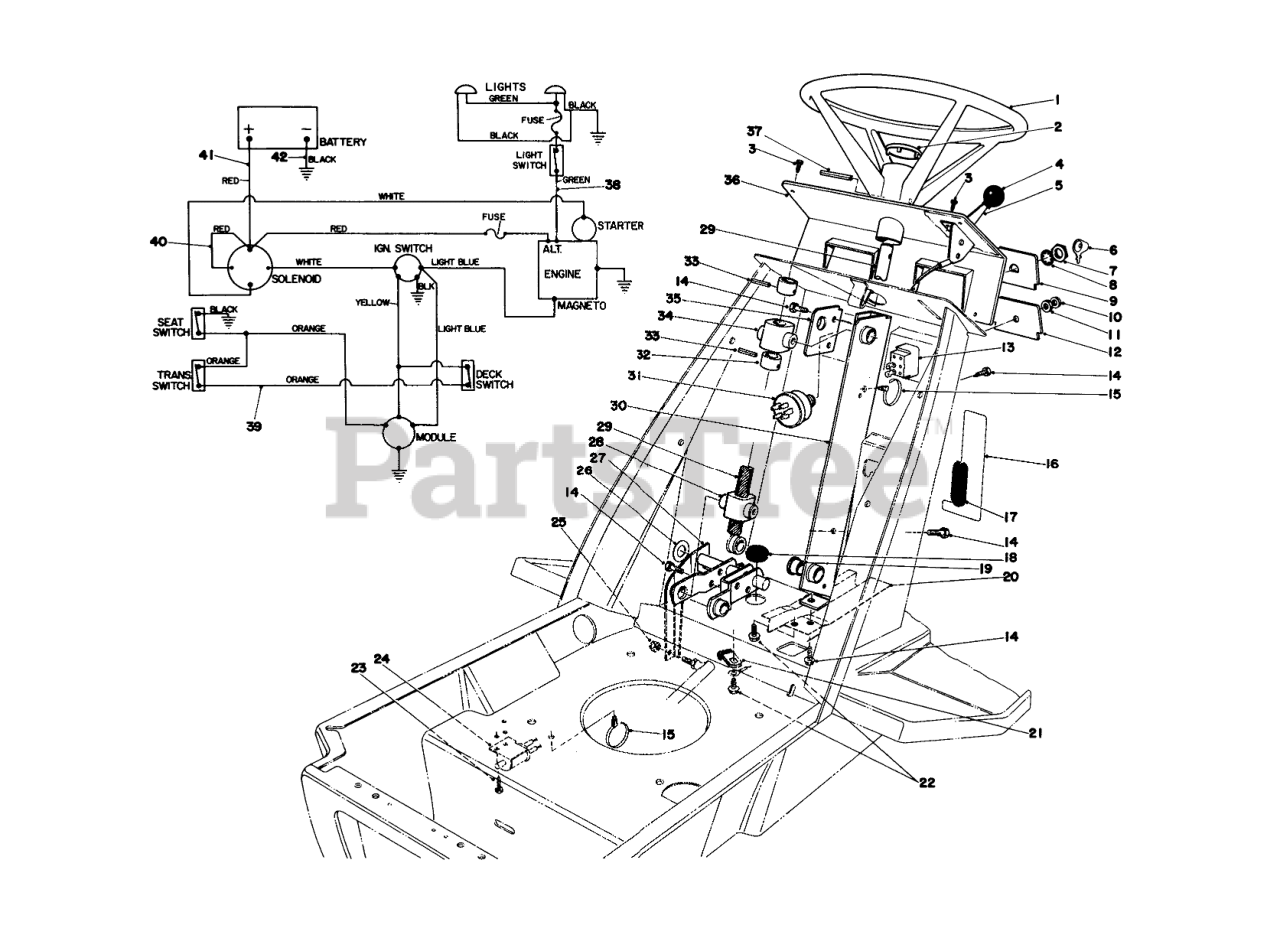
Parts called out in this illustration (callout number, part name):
1	Steering Wheel
2	STEERING WHEEL INSERT
3	SCREW-HWHTF
4	KNOB-CONTROL
5	Throttle Control (Incl. Ref. #4)
6	Key
7	NUT-HH
8	Lockwasher
9	DASH PANEL INSERT
10	NUT-BULB
11	NUT-LOCK
12	DASH PANEL INSERT
13	LIGHT SWITCH
14	SCREW-HWHTF
15	216 Washer
16	Decal-Deck
17	EDGE MOULDING
18	GROMMET
19	BEARING-FLANGE
20	WIRE HARNESS SHLD B
21	CLIP-FUEL LINE
22	SCREW-HWH
23	SCREW-TAPTITE
24	DECK INTERLOCK SWITCH
25	Nut
26	WASHER
27	STEERING LINK WA BO
28	FOLLOWER STEER SHAFT
29	STEERING SHAFT
30	STRG BRKT B
31	SWITCH-STARTER
32	STRG SHAFT COLLAR
33	PIN-SPRING
34	BRG STEERING SHAFT
35	STRG BRG SUPPORT
36	DASH PANEL
37	PIN-ROLL
38	WIRE HARNESS
39	Wire Harness
40	SOLENOID WIRE
41	WIRE ASM
42	WIRE ASM
